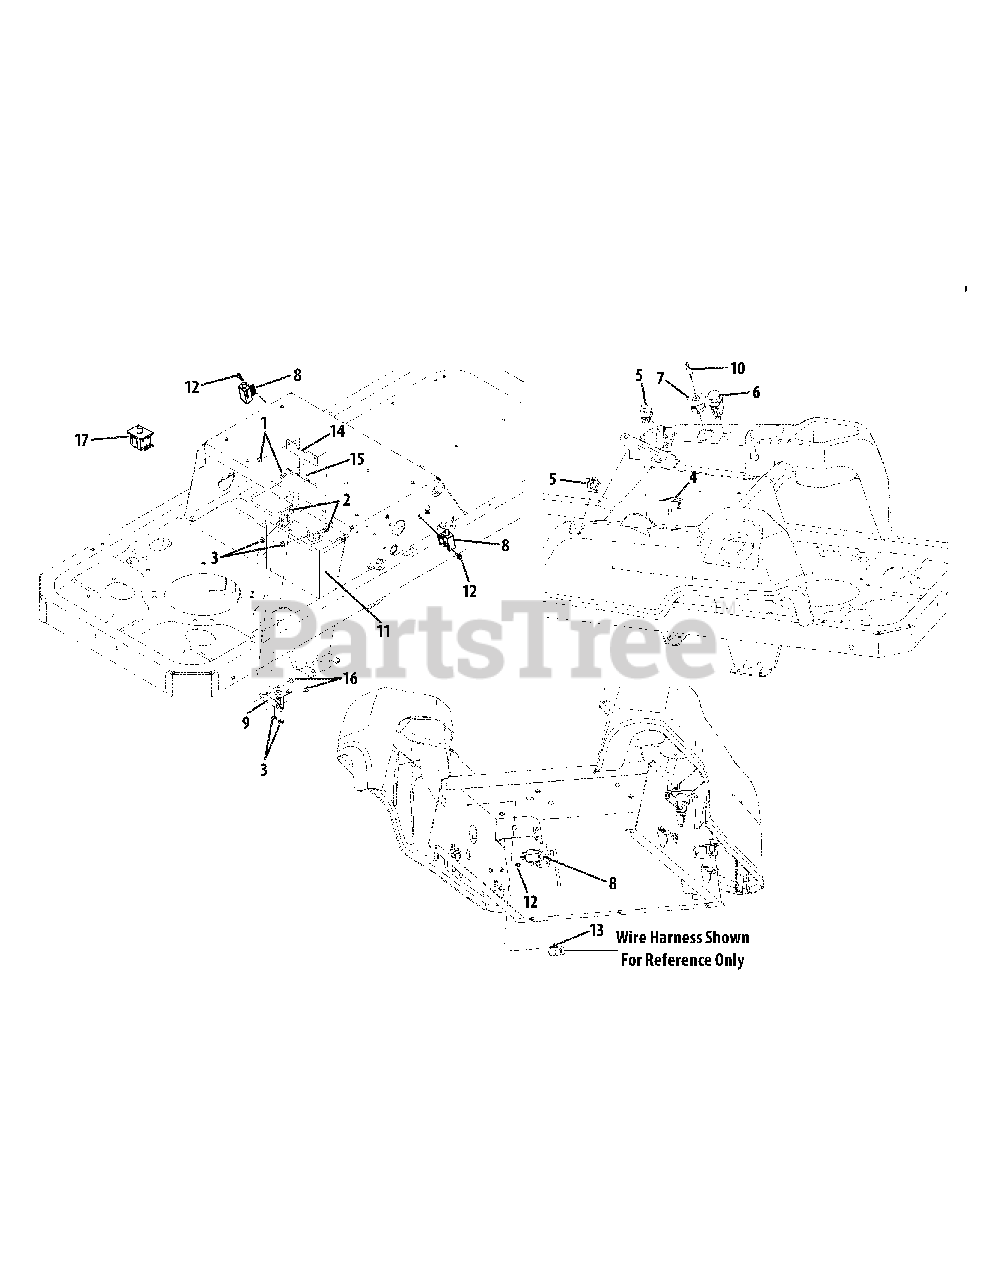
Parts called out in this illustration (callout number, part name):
1	Hex Screw, 1/4-20 x .5
2	Hex Screw, 1/4-20 x .75
3	Hex Nut, 1/4-20
5	Double Pole — Neutral Switch
6	PTO Switch
7	Ignition Switch
8	Interlock Switch
9	Solenoid
10	Key
12	Shoulder Screw, #10-32 x .500
13	Cable Tie
14	Batter Hold-down
15	Trim Strip
16	Hex Screw, 1/4-20 x .375
17	Seat Switch
